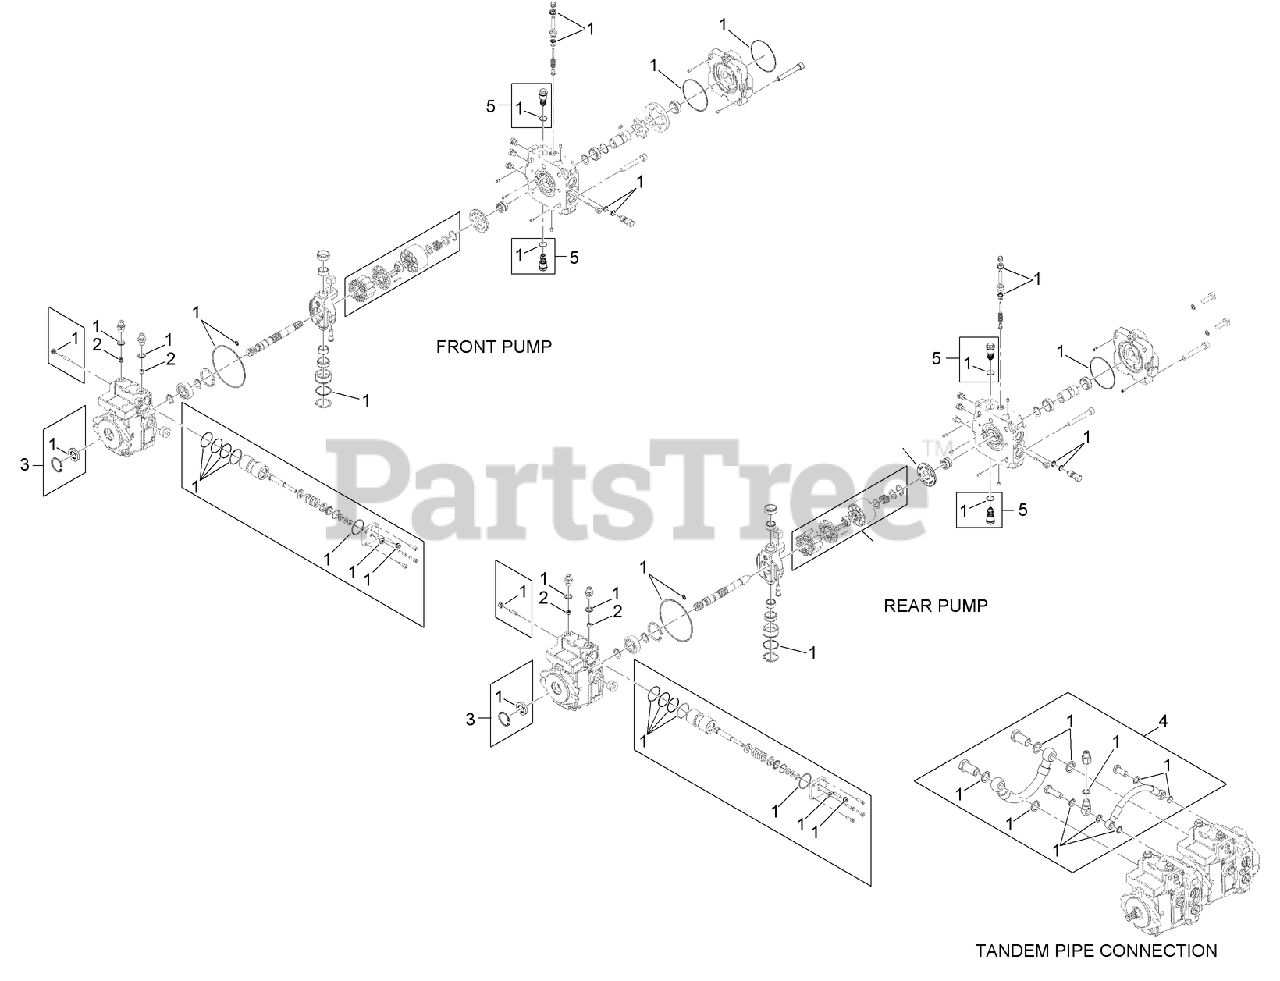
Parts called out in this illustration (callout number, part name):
1	SEAL KIT
2	SPACER-JET
3	SHAFT SEAL KIT
4	TANDEM CONNECTION PIPE KIT
5	VALVE-RELIEF
